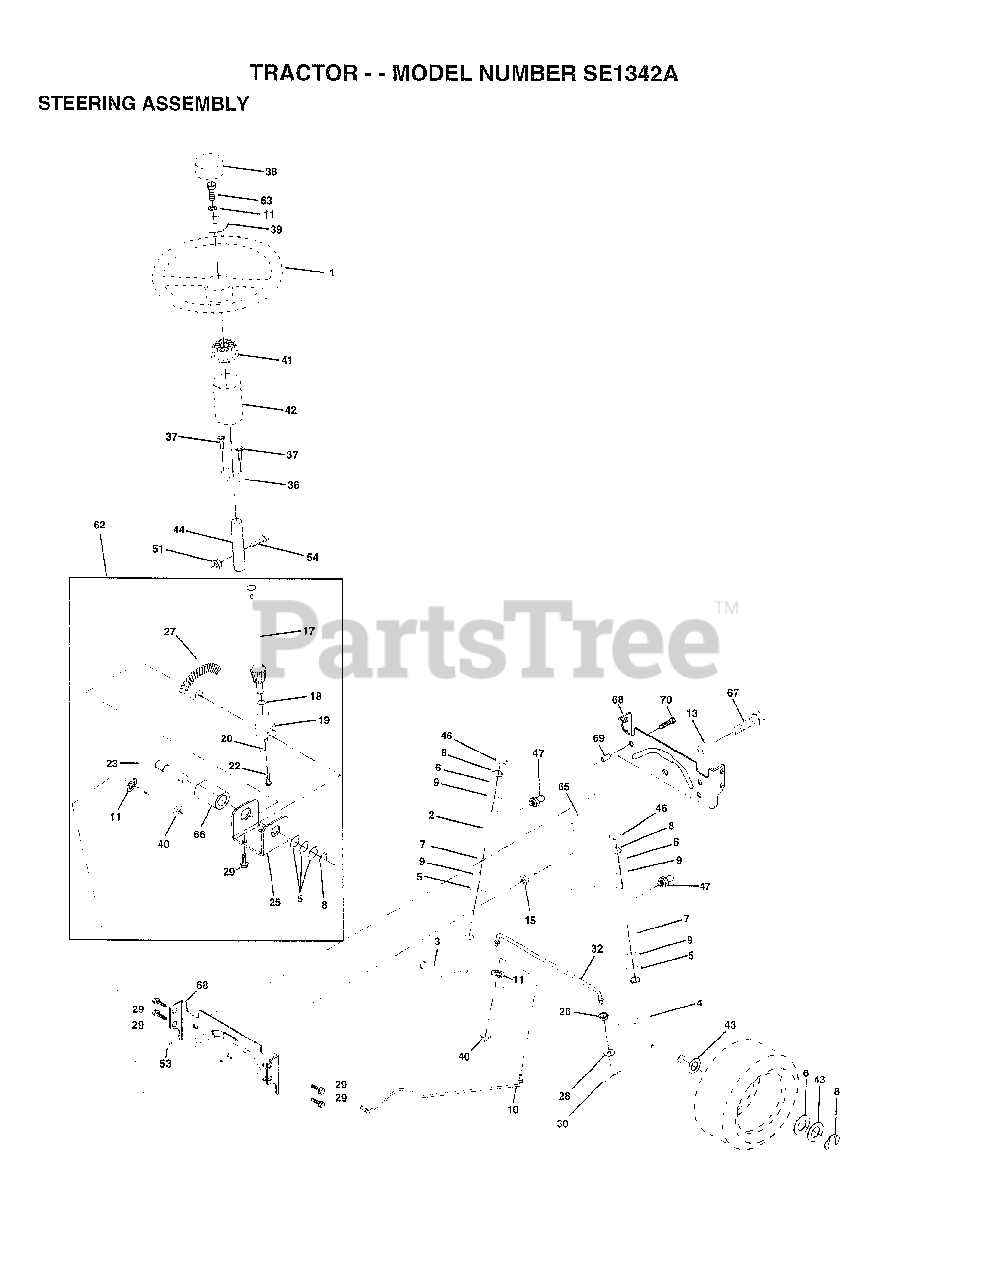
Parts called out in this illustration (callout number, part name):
1	WHEEL STR AYP BLK
2	AXLE ASM
3	SPINDLE.ASM.LH
4	"SPINDLE ASM,RH"
5	WASHER .T
6	WASHER
7	WASHER
8	RING
9	COL. SRTG. BEAR.
10	DRAGLINK-STAMPED
11	LOCKWASHER
13	BEARING AXLE
15	"NUT-LOC,FLANGE LT"
17	SHAFT ASM STEERIN
18	THRUST WASHER
19	SUPPORT.SHAFT
22	SCREW HEX SOC1/4-
25	BRKT-STEERING
26	BUSHING.DRAGLINK
27	GEAR SECTOR
28	WASHER
29	SCREW
30	COTTER PIN
32	TIE ROD
36	BUSHING.STEERING
37	"SCREW-TT,10-32 FL"
38	CAP STEER AYP
39	WASHER T
40	GRIPCO NUT
41	ADAPTER LT
42	BOOT.STEER.PL
43	WASHER
44	EXT SHAFT STEERIN
46	CAP
47	ZERK M
51	NUT
54	BOLT
62	KIT STEERING ASM
63	BOLT
65	SPACER AXLE
66	"BEARING-ARM,PITMA"
67	BOLT
68	BRACE AXLE
69	"SPACER BRCAE,AXLE"
70	BOLT.HEX.3/8-16X2
